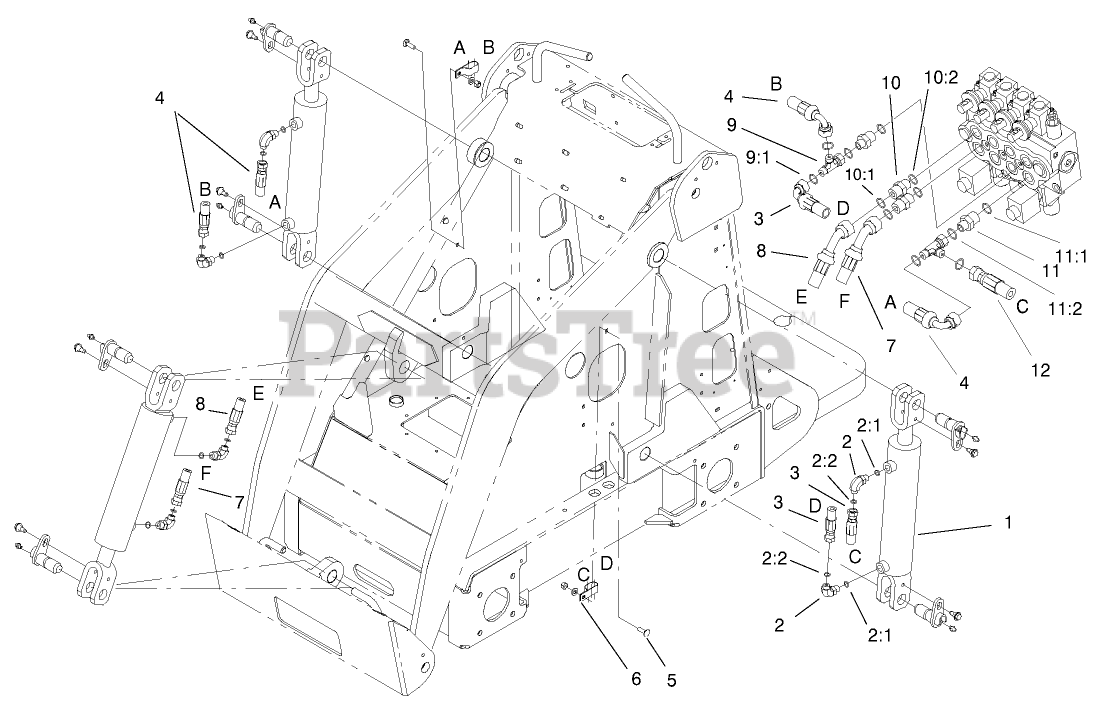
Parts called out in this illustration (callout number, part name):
1	CYLINDER KIT
2	FITTING-ELBOW 90
2:1	O-RING
2:2	O-Ring
3	HYD HOSE ASM
4	HOSE-HYD
5	BOLT-CARR
6	CLAMP-R, DOUBLE
7	HOSE-HYD
8	HOSE-HYD
9	FITTING-HYD
9:1	O-Ring
10	FITTING-STRAIGHT
10:1	O-RING
10:2	O-RING
11	FITTING-STR
11:2	O-RING
11:3	O-Ring
12	HYD HOSE ASM
